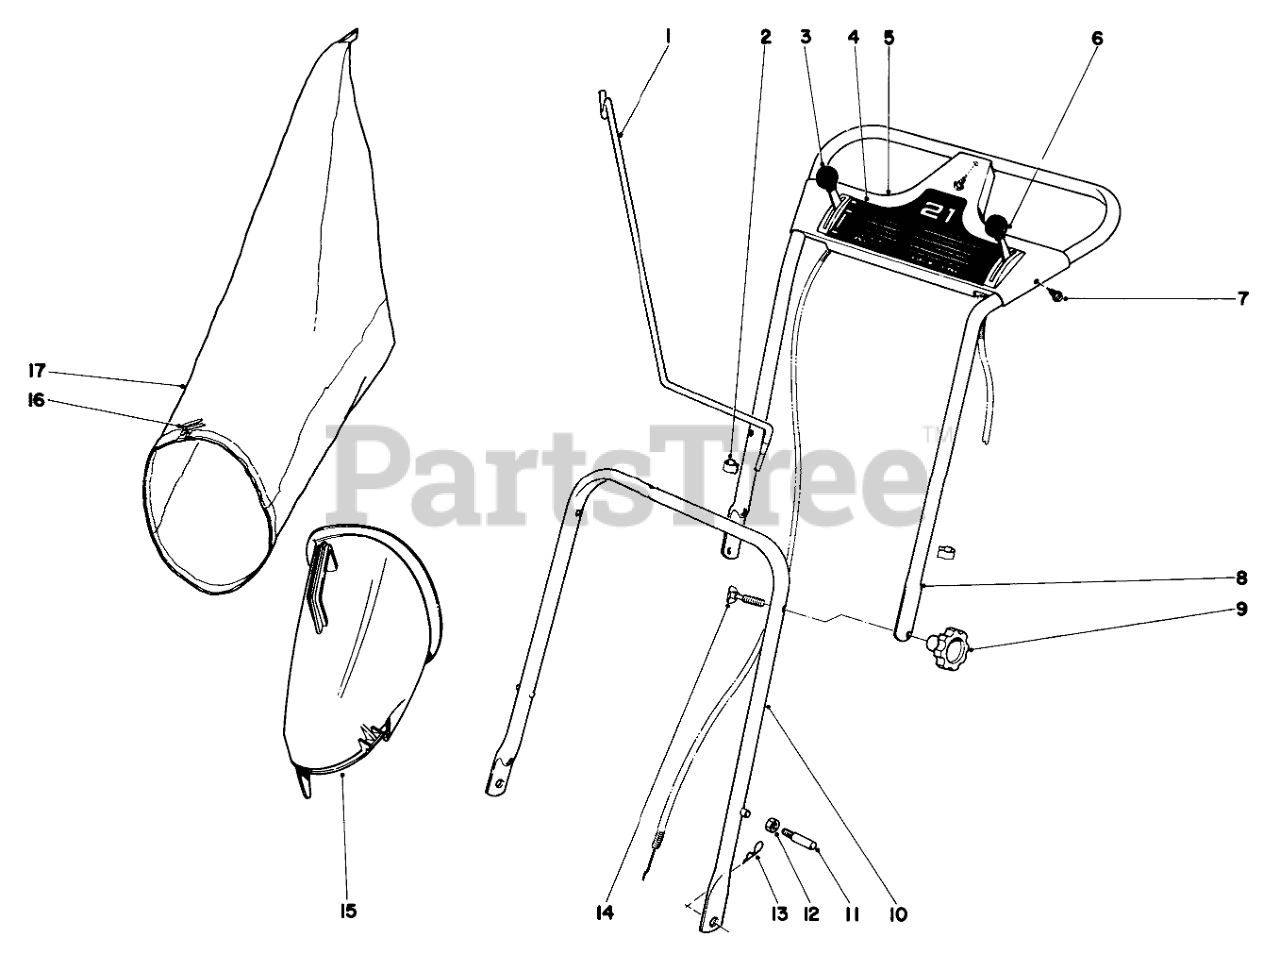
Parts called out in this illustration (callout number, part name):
1	Bag Hanger Rod
2	CONTROL WIRE CLIP
3	Throttle Control
4	Decal, Escutcheon Plate
5	Escutcheon Plate
6	Traction Control
7	SCREW-HWHTF
8	Upper Handle
9	Handle Release Knob
10	Lower Handle
11	Handle Pin
12	Nut
13	PIN-COTTER, HAIR
14	HANDLE SCREW
15	Bag Attachment
16	BAG CORD FASTENER
17	Grass Bag Kit
